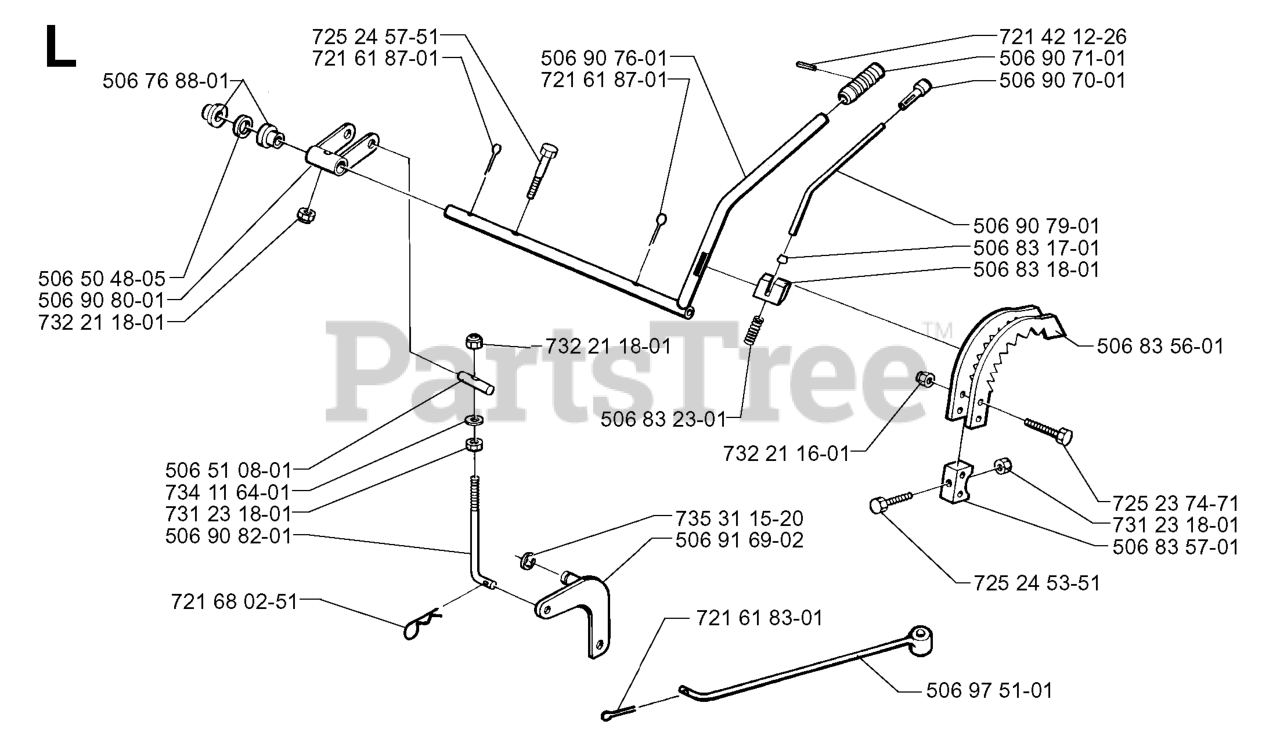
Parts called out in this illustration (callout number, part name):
1	ASSY-CABLE WIRE HARNESS
2	TRIGGER THROTTLE
3	HOUSING-THROTTLE (RH)
5	FLEX SHAFT 52"
6	SCREW M4 X 1.75 PT 16MM
7	SPRING TRIGGER
8	KIT-DRIVESHAFT
9	CLAMP ASSIST HANDLE
10	WINGNUT, TYPE 2
11	HSG THROTTLE LH
12	KIT SWITCH
13	HANDLE ASSIST
14	BOLT, TYPE 2
15	SHIELD ASSY
16	KIT - LIMITER - LINE
18	BOLT, TYPE 2
